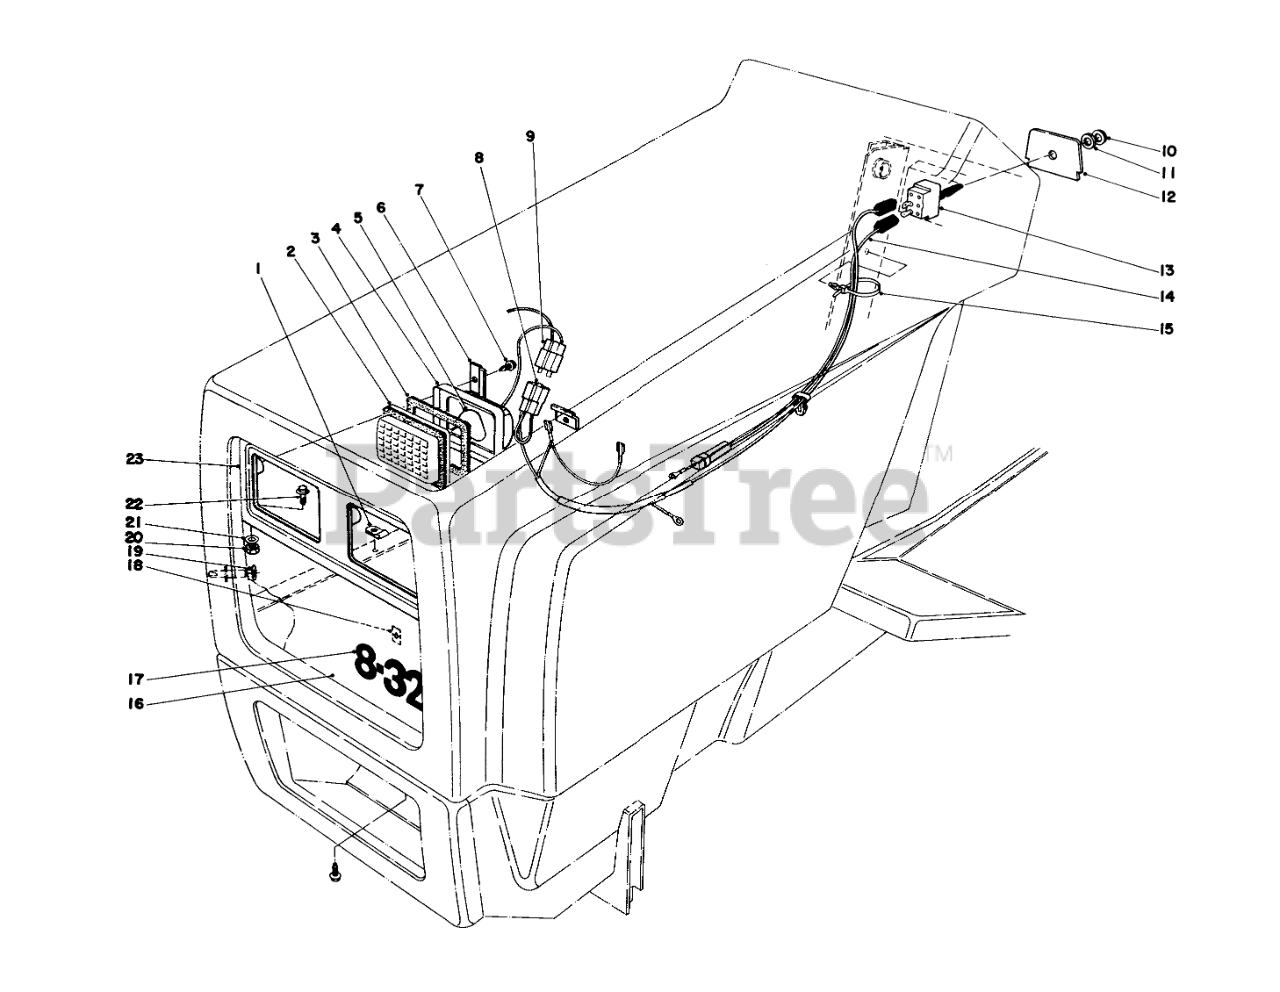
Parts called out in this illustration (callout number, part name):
1	CABLE CLAMP
2	Lens
3	Gasket Lens
4	Reflector
6	HEADLIGHT CLAMP
7	SCREW-HWHTF
8	Connector
9	SOCKET
10	Facenut
11	Locknut
12	DASH PANEL INSERT
13	Light Switch
14	WIRE HARNESS
15	TIE-CABLE
16	Grille Headlight
17	Nameplate Grille
19	WASHER
20	NUT-LOCK, SIDE
21	WASHER-FLAT
22	SCREW-SHWH
23	HEADLIGHT PANEL B
